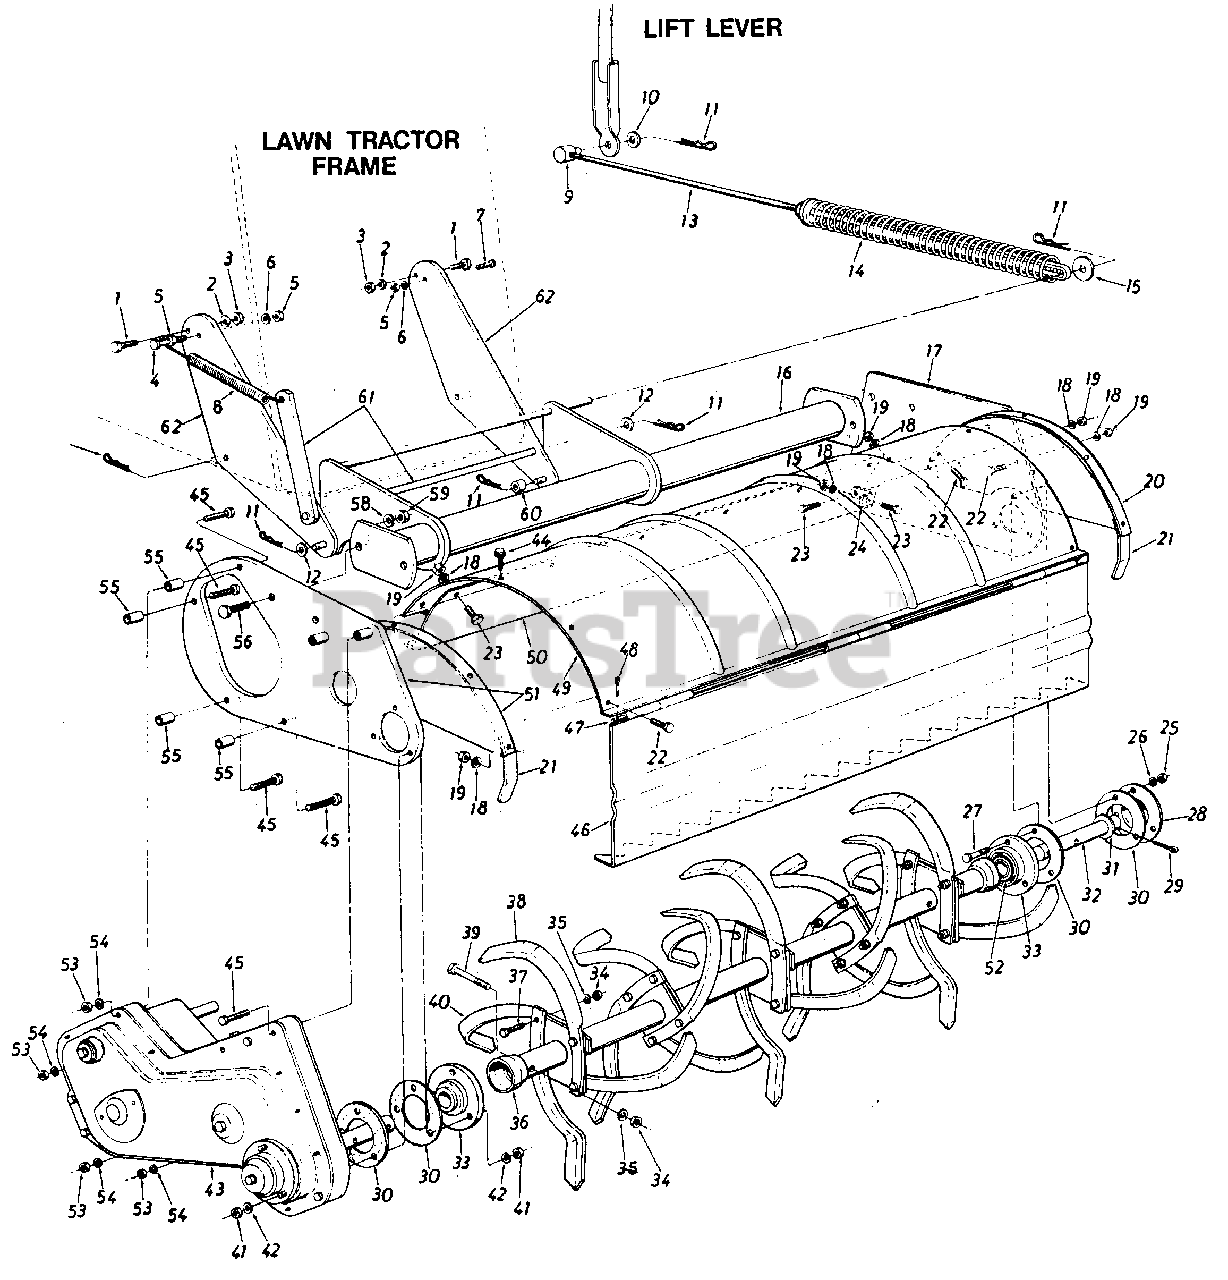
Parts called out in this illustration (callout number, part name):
1	Hex Boit 3/8-24x .88" Lg.
2	L.-Wash. 3/8" I.D. Heavy Duty
3	Hex Nut3/8-24 Thd.
4	Hex Bolt 5/16-24 x 1.50" Lg.
5	Hex Nut 5/16-24 Thd.
6	L.-Wash. 5/16" I.D.
7	Hex Bolt 5/16-24 x 1.00" Lg.
8	Extension Spring .56" O.D. x 7.75" Lg.
9	Adjustment Ferrule 1/2-13 Thd.
10	Fl.-Wash. .640" I.D. x 1.24" O.D. x .060
11	Intern. Cotter Pin 1/2" Dia.
12	Fl.-Wash. .510" I.D. x 1.0" O.D. x .060
13	Lift Rod Ass'y. 39.0" Lg.
14	Compression Spring 1.50" O.D. x 15.0" Lg.
15	Fl.-Wash. .51" I.D. x 1.50" O.D. x .075
16	Pivot Bracket Assembly
19	Hex Nut 5/16-24 Thd.
23	Hex Bolt 5/16-24 x .62" Lg.
24	Chute Pivot Bracket
25	Hex Cent. L-Nut 5/16-18 Thd.
26	L.-Wash. 5/16" I.D.
27	Hex Bolt 5/16-18 x 1.0" Lg. (Grade 5)
30	Gasket for Brg. Housing
31	Fl.-Wash. 1.25" I.D. x 2.00" O.D. x .06
32	Tine Shaft R.D. 1.25" Dia. x 6.25" Lg.
33	Bearing Housing w/Bearing
34	Hex Nut 3/8-24 Thd.
35	L.-Wash. 3/8" I.D. Heavy Duty
41	Hex Cent. L.-Nut 5/16-18 Thd.
42	L.-Wash. 5/16" I.D.
43	Chain Case Ass'y. Comp.
44	Hex Wash. TT Tap. Scr. 5/16- 18 x .62" Lg.
45	Hex Bolt 1/4-20 x 2.75" Lg.
48	Cotter Pin 1/8" Dia. x 1.00" Lg.
53	Hex Nut 1/4-20 Thd.
54	L.-Wash. 1/4" I.D.
55	Spacer.28" I.D. x .62" O.D. x .90" Lg.
56	Hex Bolt 1/2-13 x 1.00" Lg.
58	L.-Wash. 1/2" I.D.
59	Hex Nut 1/2-13 Thd.
60	Spacer.50" I.D. x 1.00" O.D. x.50" Lg.
61	Idler Bracket Support Arm Ass'y.
62	Pivot Bracket Support
